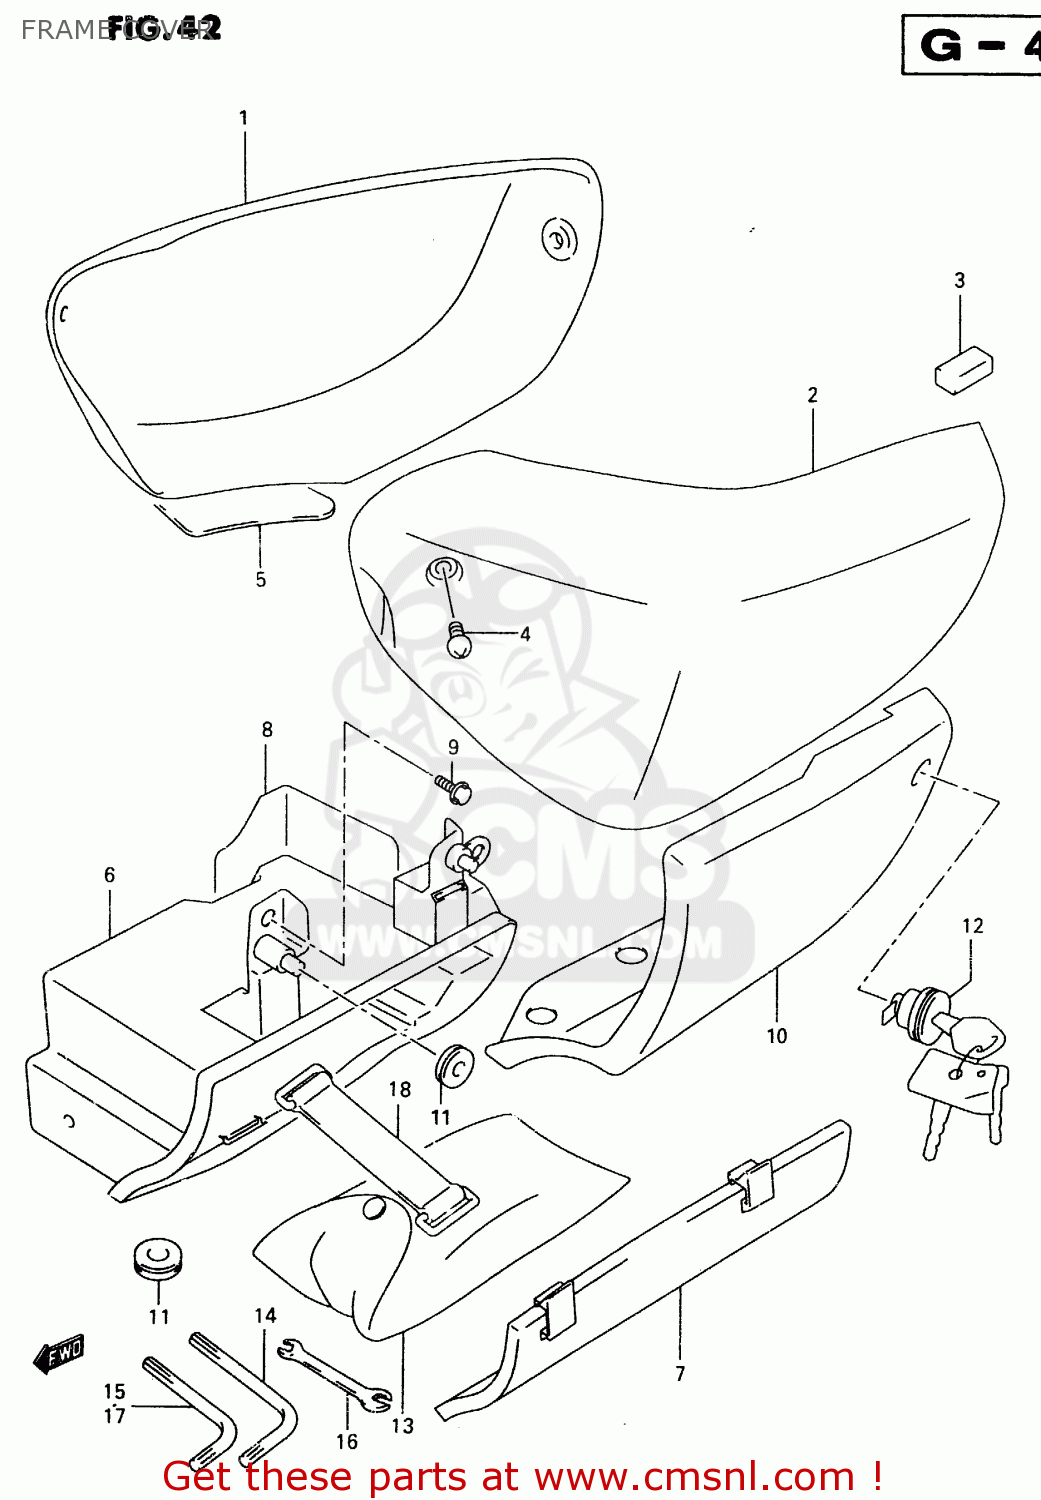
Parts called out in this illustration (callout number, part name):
1	COVER,FRAME,R(BLACK)
2	COVER,FRAME,L(BLACK)
3	CUSHION,FRAME COVER
4	SCREW(6X16)
5	SHIELD,FRAME COVER,R
6	BODY,TOOL HOLDER
7	CAP,TOOL HOLDER
8	SHIELD,TOOL HOLDER BODY
9	BOLT(6X16)
10	COVER,TOOL HOLDER
11	CUSHION
12	LOCK SET,COVER
13	TOOL ASSY
14	HEXAGON SPANNER,12
15	SPANNER,HEXAGON(4)
16	OPEN SPANNER(8X10)
17	HEXAGON SPANNER,5
18	BAND
